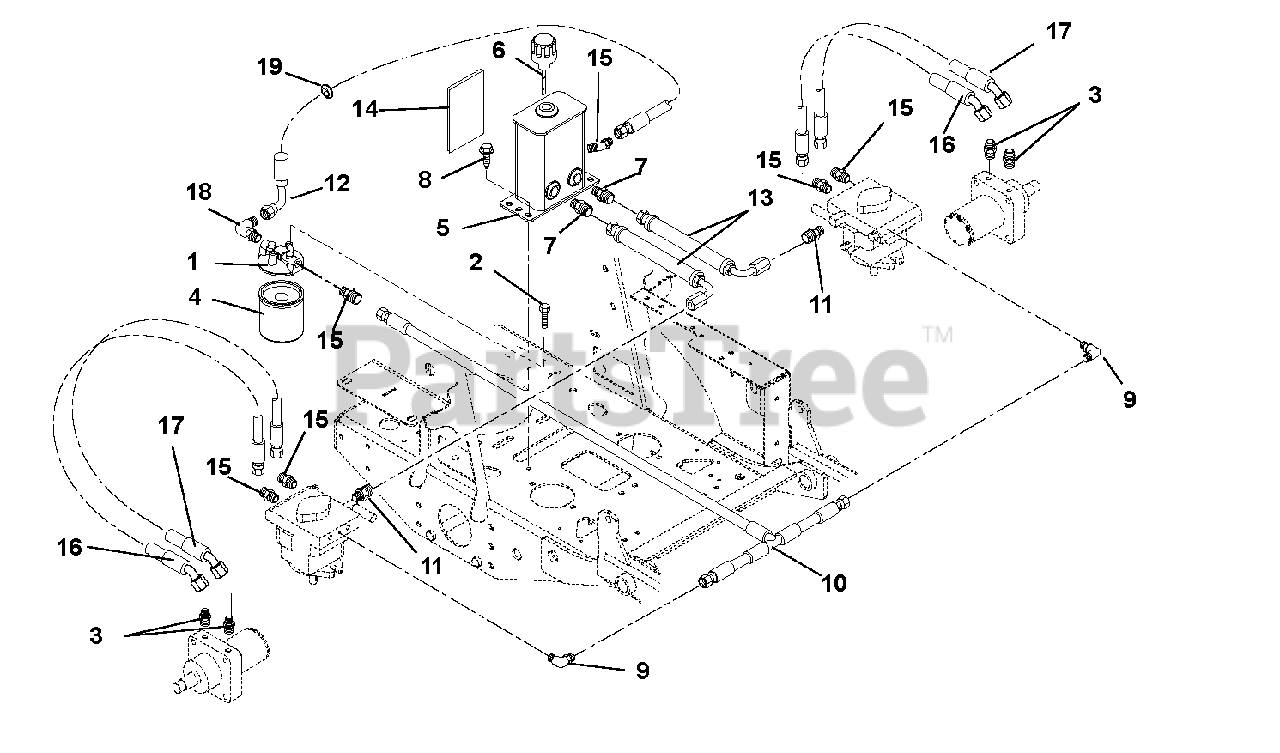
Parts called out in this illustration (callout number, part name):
1	Head, Filter
2	Bolt, Hex .25-20 x .50 Grade 5
3	Adapter, Hydraulic
4	Oil Filter
5	Weldment, Formed Hydraulic Tank – 3 Port
6	Breather Dipstick
7	Fitting, Hydraulic Straight M8O-M4F
8	Screw, Tapping .38-16 x .50 Hex Washer Head
9	Adapter, Hydraulic 8MB-12FPX90
10	Hose, Hydraulic .50 to .38 Tee Assembly
11	Fitting, Hydraulic (4-6 F5OLO)
12	Hose, Hydraulic .50-11-OK F8F0-F8F9
13	Hose, Hydraulic
14	Shield, Heat 5.50 x 4.50
15	Adapter, Face Seal 8 x 8 1/2 O-Ring 8 F5OLO, Steel
16	Hose, Hydraulic .50-11-3K
17	Hose, Hydraulic .50-12-3K
18	Fitting, Hydraulic EL M8F-M80
19	Grommet, 1.25 I.D. x 1.50 O.D.
